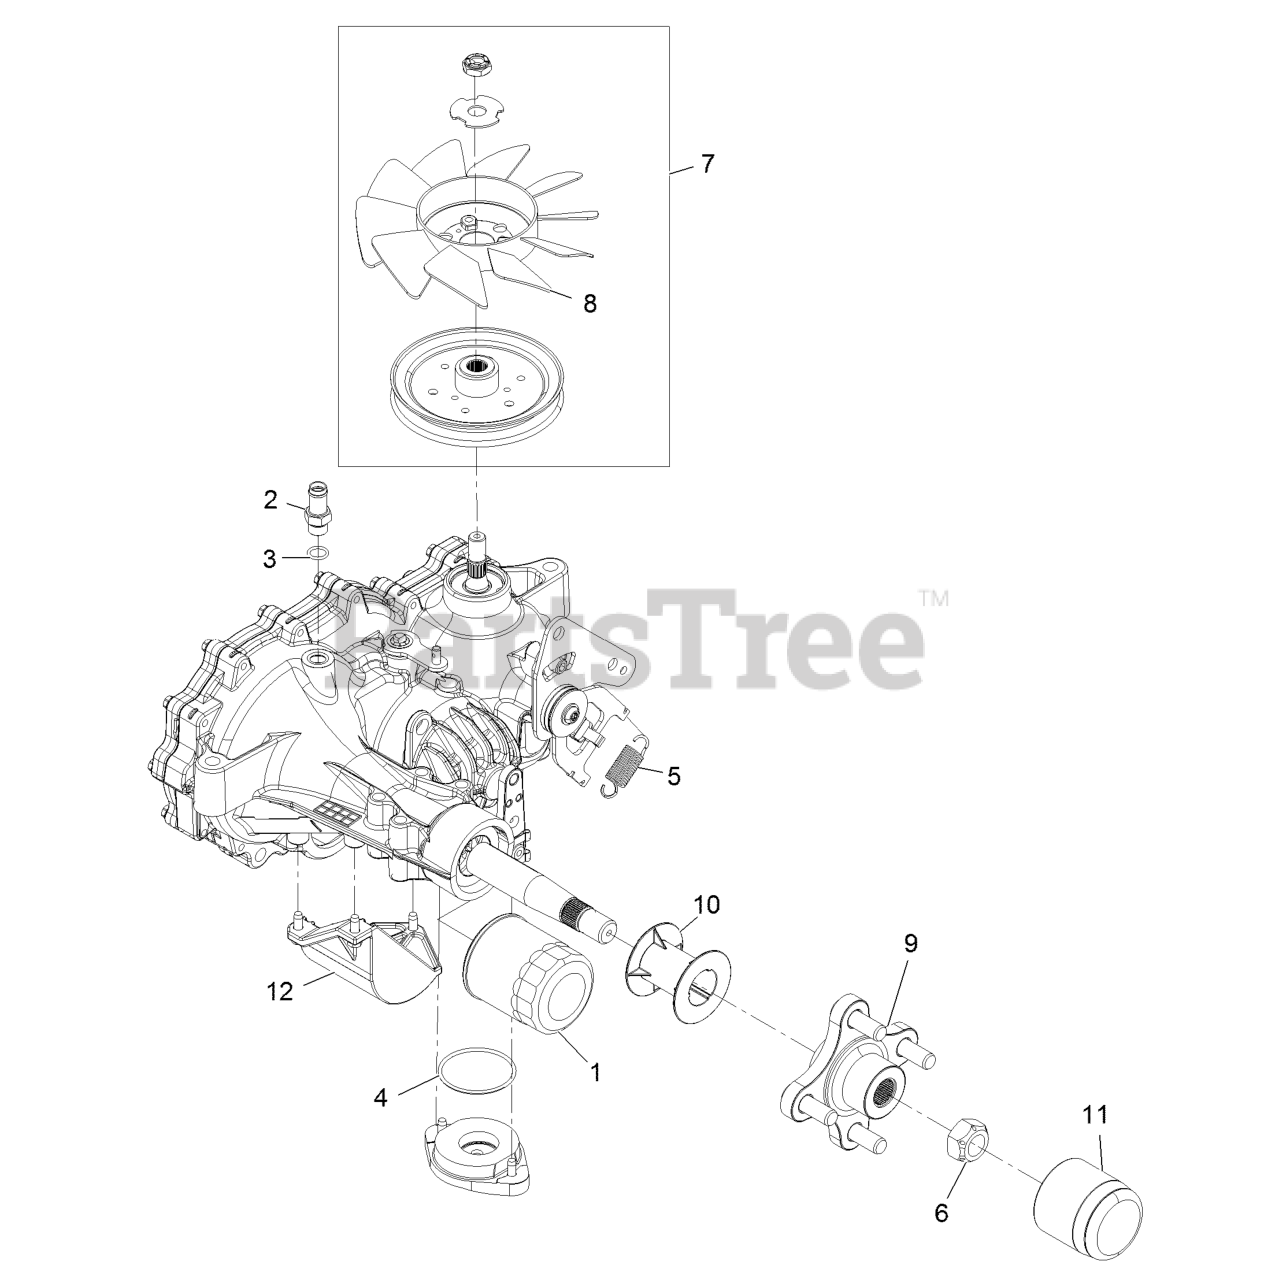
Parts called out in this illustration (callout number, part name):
1	ELEMENT-OIL FILTER, HYD
2	ADAPTER-STRAIGHT
3	O-RING
4	O RING-SEAL
5	SPRING-EXTENSION
6	NUT-HUB
9	HUB-OFFSET
10	TUBE-AXLE
11	CAP-AXLE, LONG
12	GUARD-FILTER, LH
